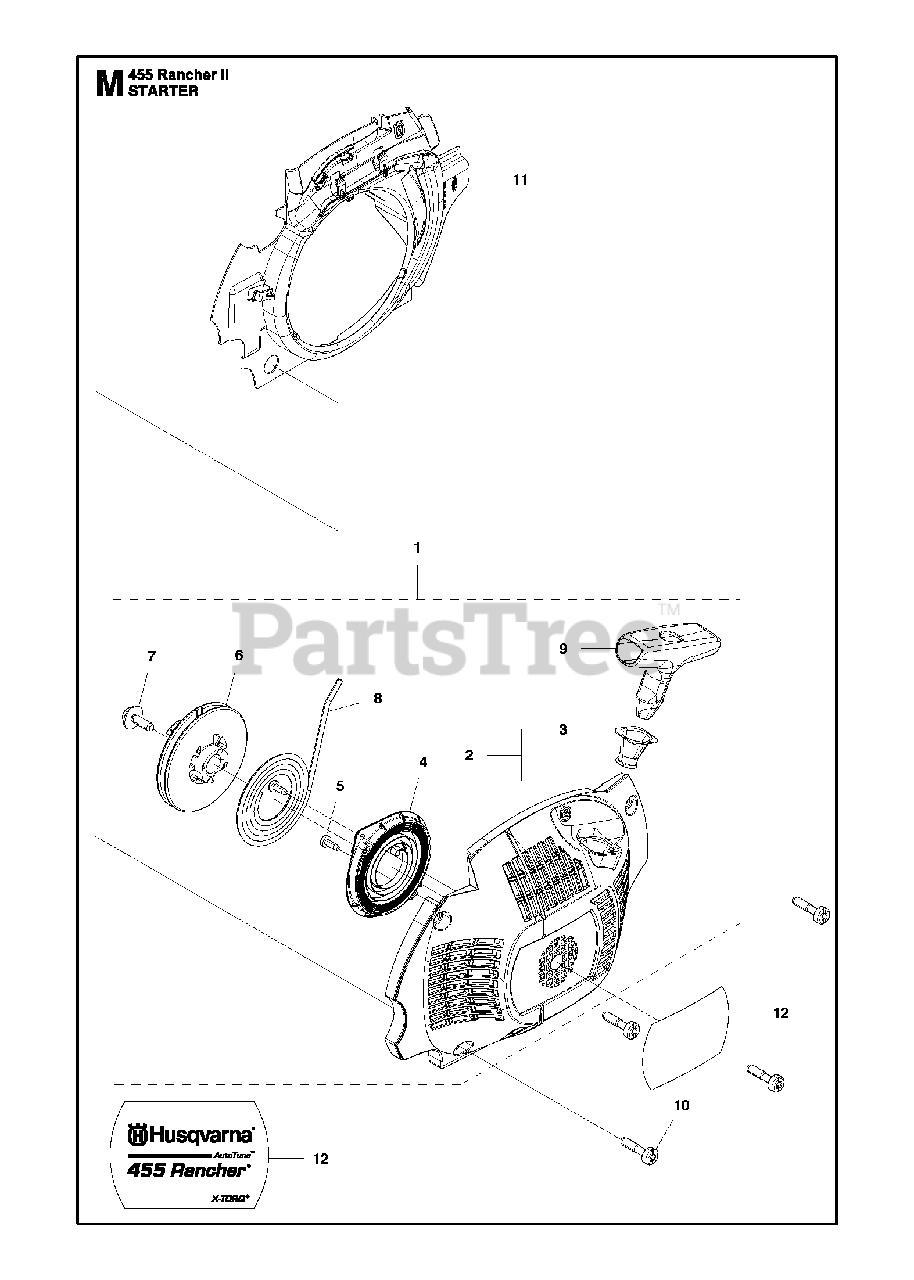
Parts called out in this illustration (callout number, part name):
1	STARTER ASSY
2	STARTER HOUSING
3	SLEEVE
4	SPRING CASSETTE ASSY
5	SCREW
6	PULLEY
7	SCREW
8	STARTER ROPE
9	HANDLE
11	AIR BAFFLE
12	DECAL STARTER 455
